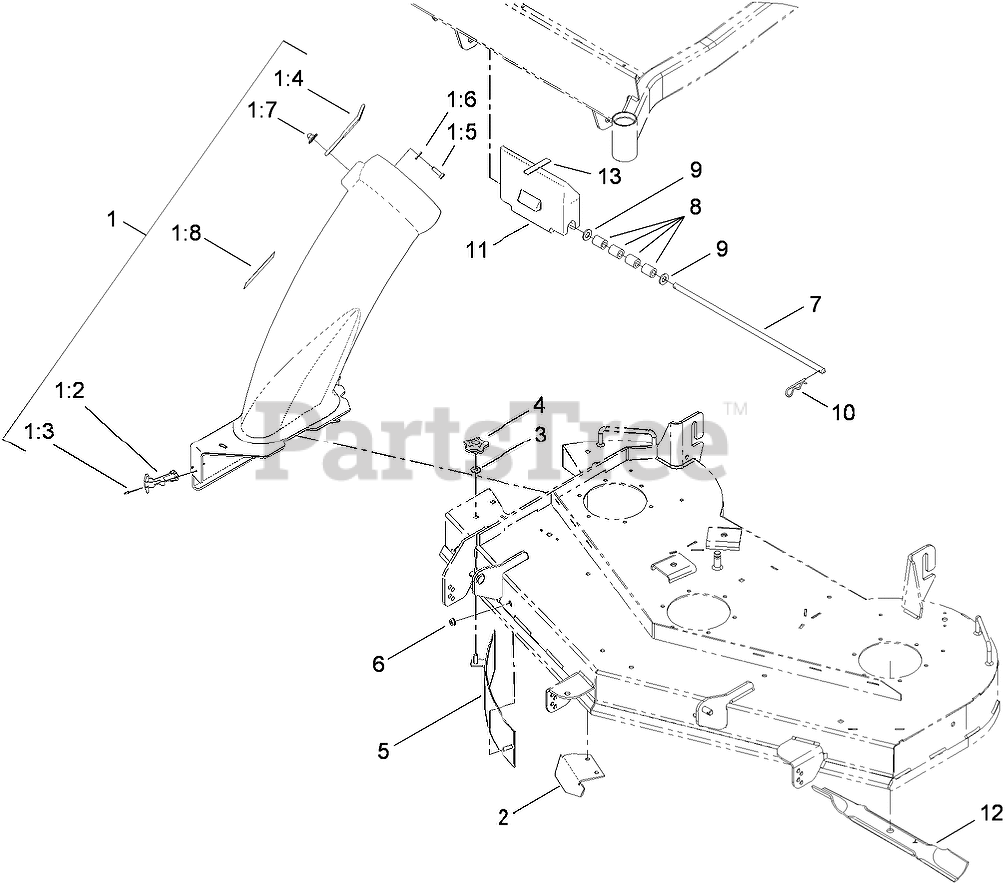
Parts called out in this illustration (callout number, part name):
1	54 INCH CHUTE ASM
1:2	HANDLE ASM
1:3	RIVET-POP
1:4	RETAINER-DUCT
1:5	SCREW-HH
1:6	WASHER-FLAT
1:7	NUT-IMPELLER
1:8	DECAL-DANGER
2	BAFFLE-CUTOFF
3	WASHER-FLAT
4	KNOB-LOCKING
5	BAFFLE-BAGGER
6	NUT-HF, NI
7	ROD-DECK, PIVOT
8	SPACER-WHEEL
9	WASHER-FLAT
10	PIN-HAIR
11	WEIGHT-BAGGER
12	BLADE-HI LIFT, 18.75 INCH
13	BUMPER-PAD
